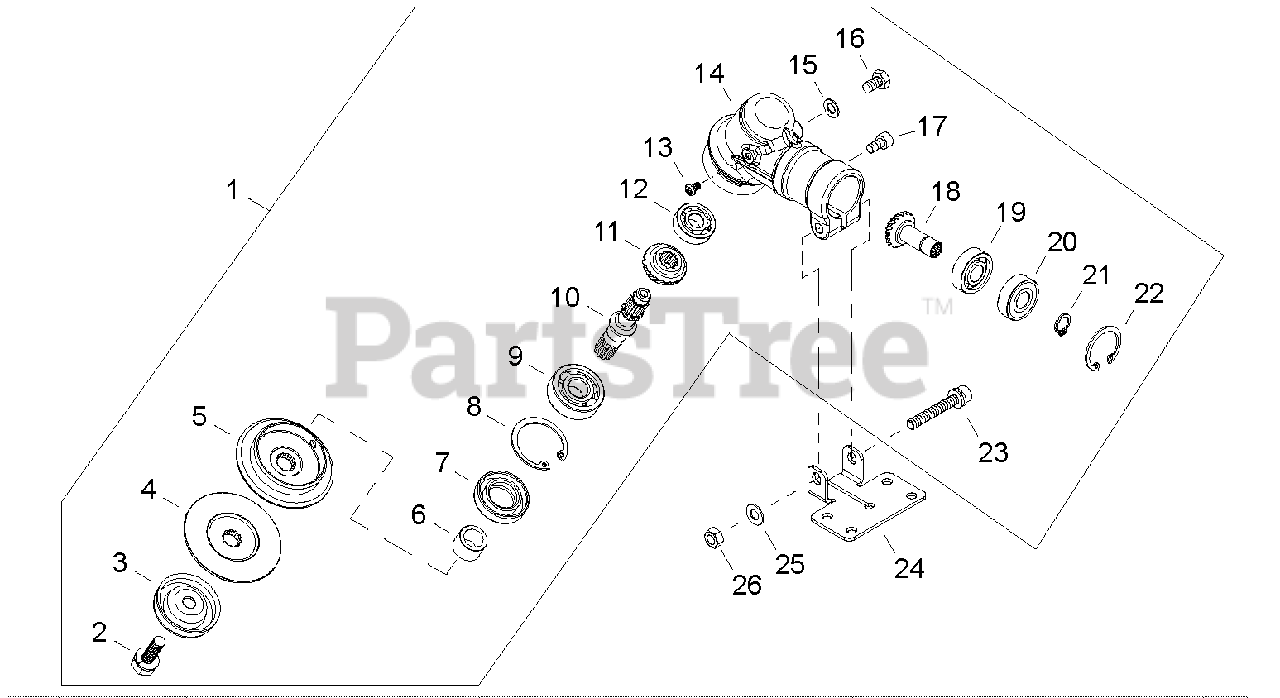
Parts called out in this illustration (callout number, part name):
1	GEAR CASE ASSY
2	BOLT M8×22
3	GUARD, BOLT
4	PLATE, ADAPTOR - LOWER
5	PLATE, ADAPTOR - UPPER
6	SPACER
7	SEAL, OIL
8	RING, SNAP Ø32
9	BEARING, BALL 6201C
10	SHAFT, GEAR
11	GEAR, BEVEL
12	BEARING, BALL 609
13	SCREW M4×6
14	CASE, GEAR
15	WASHER 6.5×11.5×0.8
16	BOLT M6×10
17	BOLT M5×10
18	PINION, BEVEL Ø8
19	BEARING, BALL 6001
20	BEARING, BALL 6000Z
21	RING, SNAP Ø10
22	RING, SNAP Ø26
23	BOLT M6×40
24	PLATE, SHIELD MOUNTING
25	WASHER 6.5×13×1
26	NUT, HEX M6
